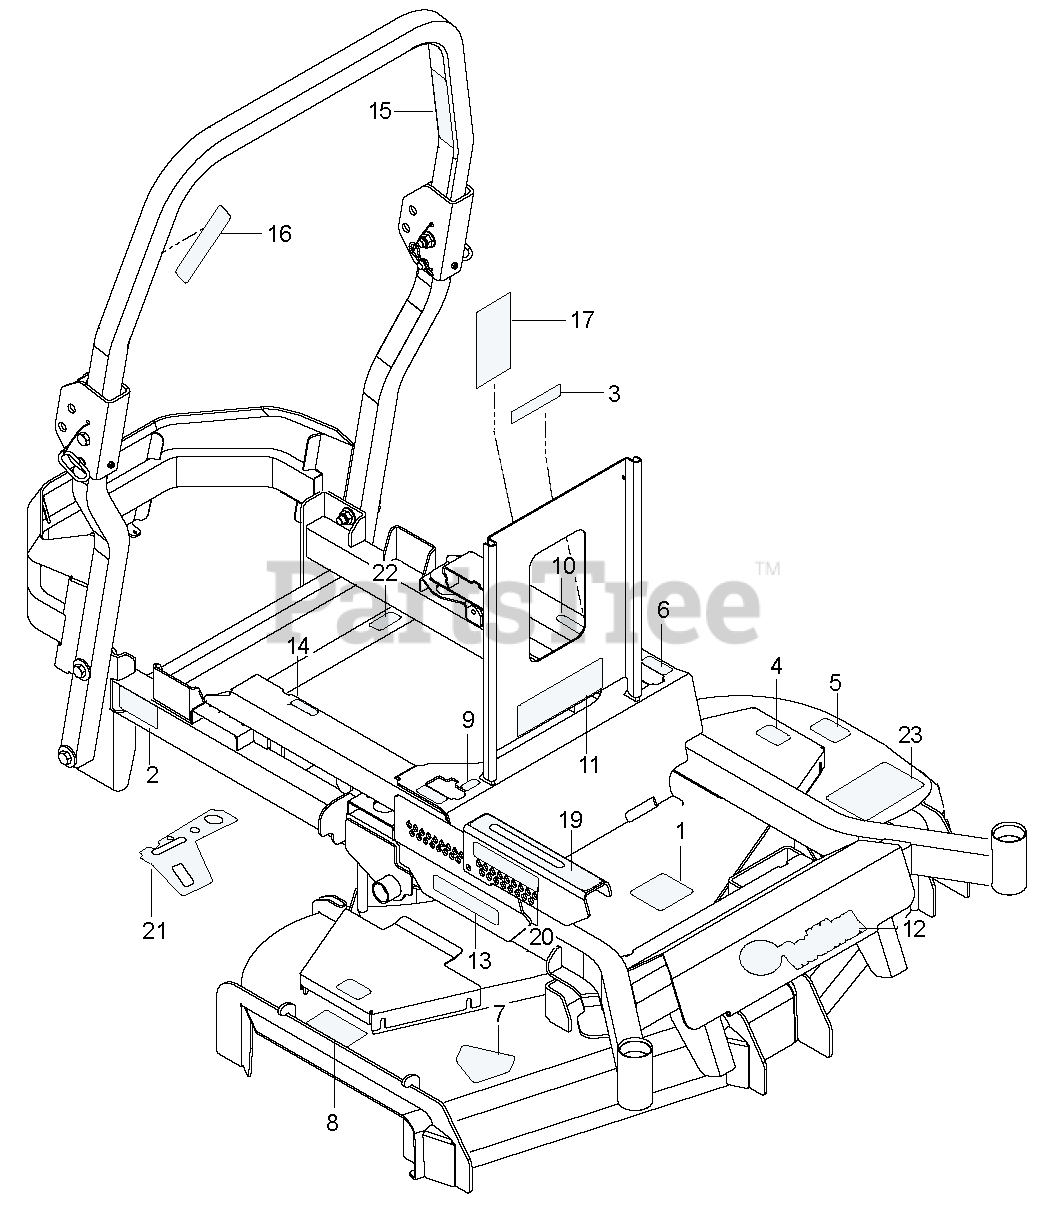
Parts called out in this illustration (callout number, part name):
1	DECAL, BELT ROUTING
2	DECAL, BELT DRIVE
3	EURO DECAL-BATTERY WARNIN6
4	DECAL.DECK.6MIL.EURO.NOSTEP
5	DECAL DECK DECAL DECAL.DECK.54
6	DECAL.ZTR.MTNCONTROL.2015.PPRO
7	DECAL, DECK DEFLECTOR, WARNING
8	DECAL.DECK.6MIL./DEF.SHLD.WARN
9	DECAL.ZTR.TRACKING.GRAPHIC
10	DECAL.ZTR.TRACKING.GRAPHIC
11	DECAL ZTR WARNING DECAL DECAL.
12	DECAL ZTR BRAND GRAPHIC DECAL.
13	DECAL ZTR SIDE RAIL GRAPHIC DE
14	DECAL ZTR INSTRUCTION GRAPHIC
15	DECAL ROPS DECAL DECAL.ROPS.PZ
16	DECAL, ROPS, WARNING
17	DECAL, SERVICE
19	DECAL ZTR INSTRUCTION GRAPHIC
20	DECAL ZTR INSTRUCTION GRAPHIC
21	DECAL ZTR CONTROL PANEL DECAL.
22	DECAL ZTR INSTRUCTION GRAPHIC
23	FOOT PAD
